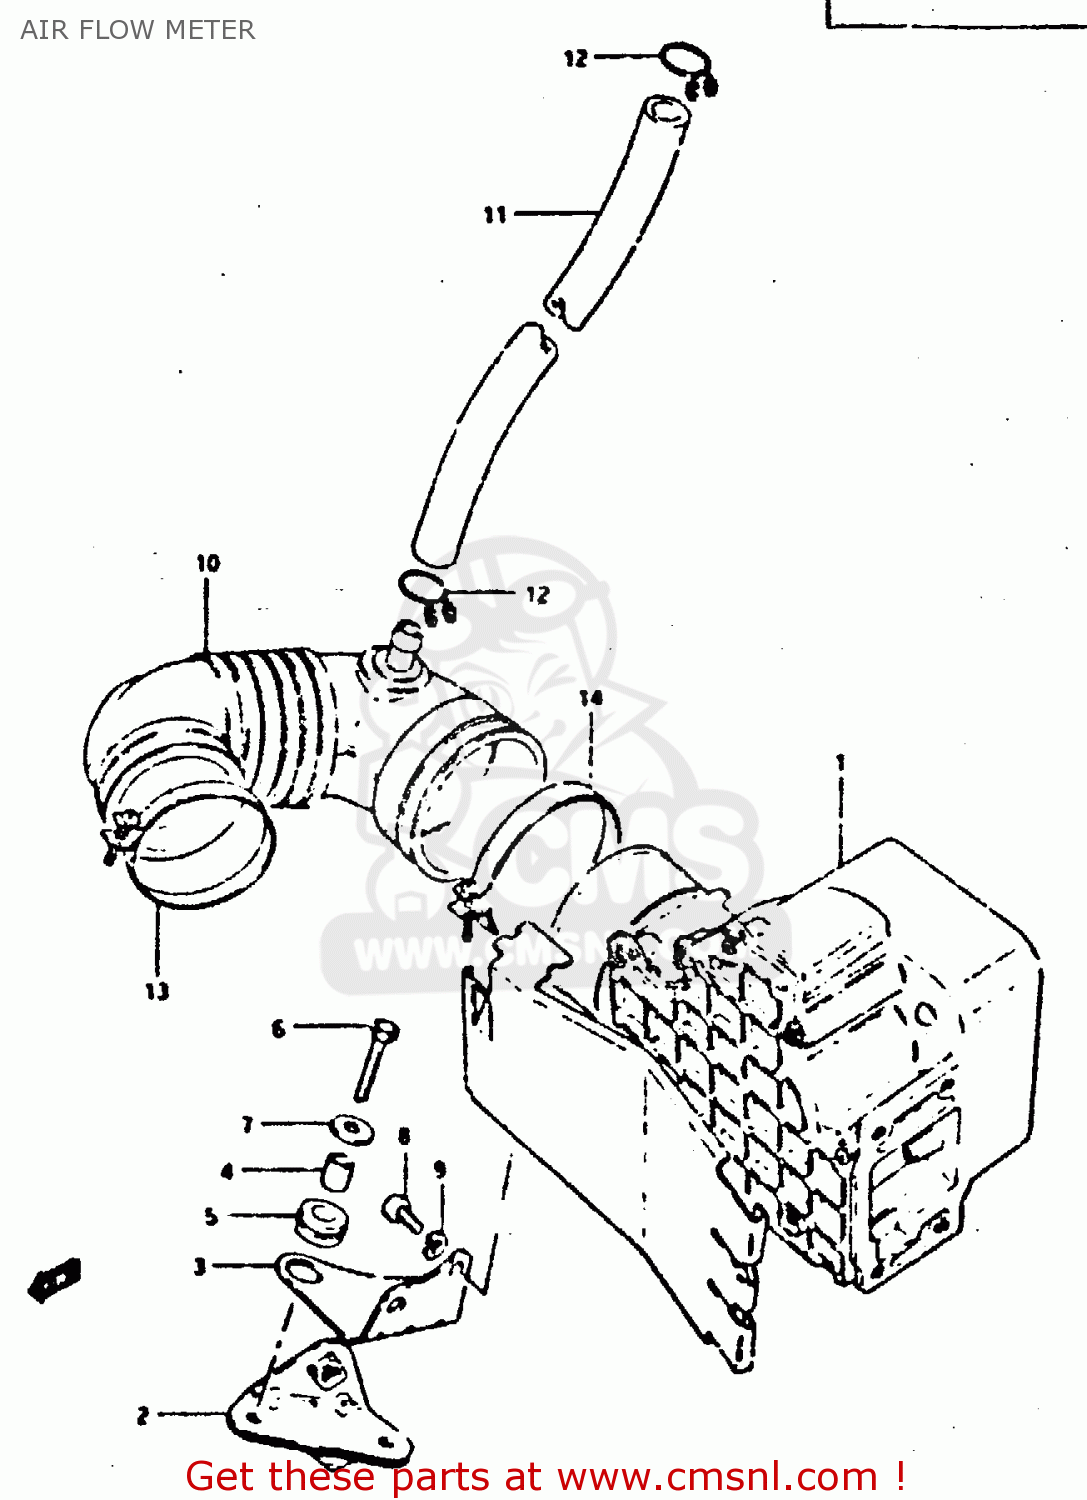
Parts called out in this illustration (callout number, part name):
1	METER ASSEMBLY,AIR FLOW
2	BRACKET (1)
3	BRACKET (2)
4	SPACER (6.8X10X10)
5	CUSHION
6	BOLT
7	WASHER
8	SCREW 6X12
9	LOCK WASHER
10	HOSE ASSY, AIR FLOW METER
11	HOSE, BREATHER (L:420)
12	CLIP
13	CLAMP
14	CLAMP
